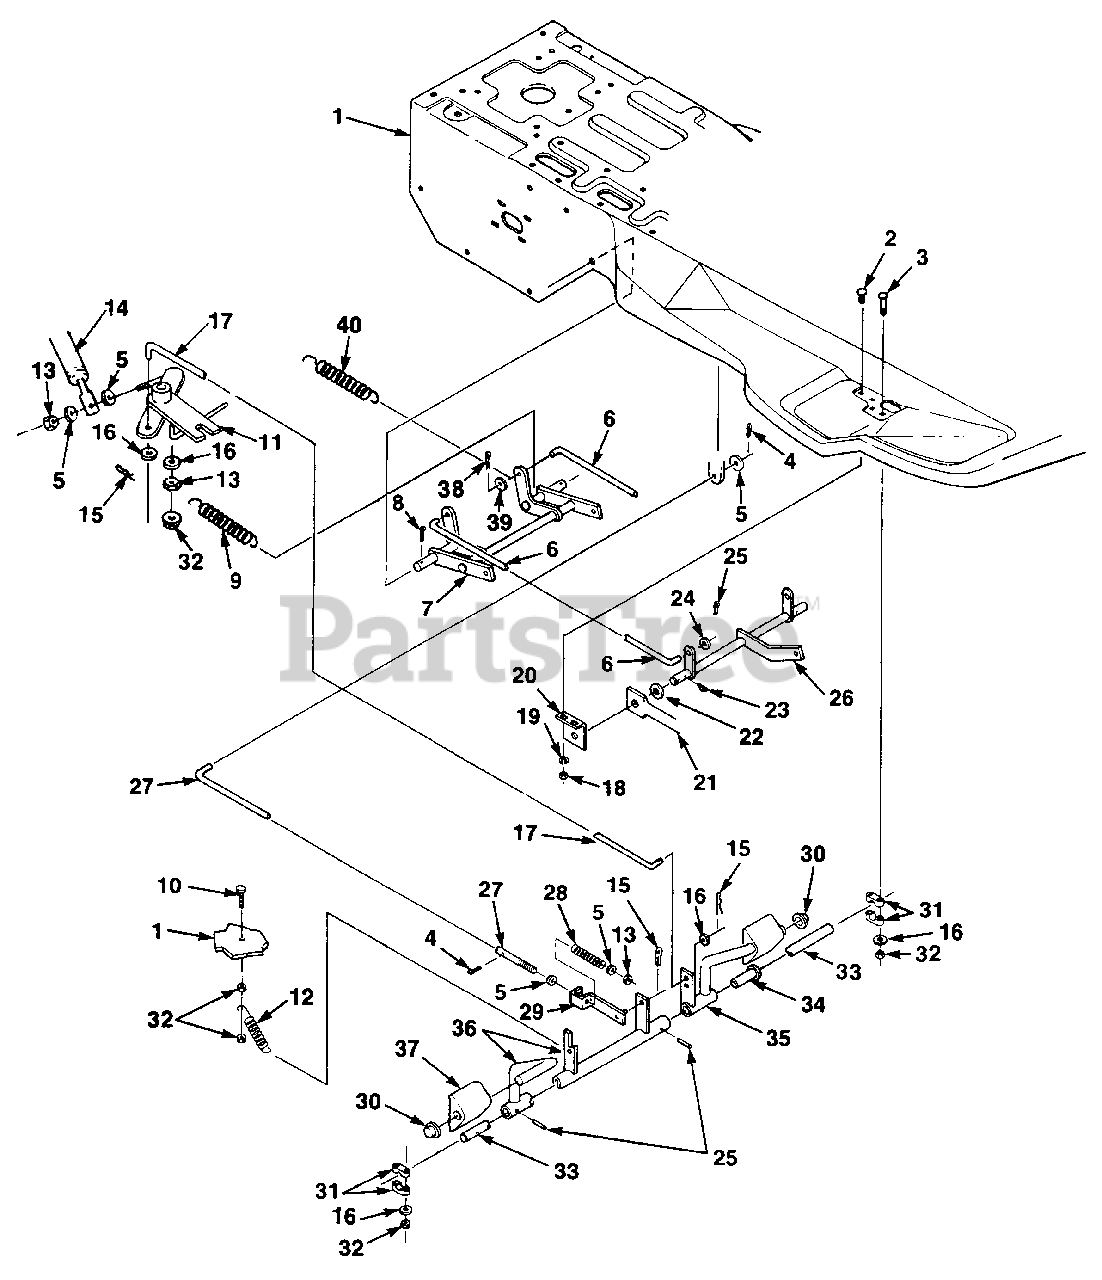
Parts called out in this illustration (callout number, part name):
2	BOLT- Carr. 1/4-20 x 5/8
3	BOLT- 1/4-20 x 1 1/2
4	PIN- Cotter
5	WASHER- 5/16 Plain
6	ROD- Deck lift
7	HANGER- Rear
8	PIN- Cotter
9	SPRING- Extension
10	SCREW- 1/4-20 x .625
11	ARM- Pivot
12	SPRING- Extension
13	NUT- Hex 5/16-18
15	PIN- Cotter
16	WASHER- 1/4"
17	ROD- Clutch
18	NUT- Hex 1/4-20
19	WASHER- Lock 1/4
21	SUPPORT- Front axle
22	WASHER- Flat 1/2
23	PIN- Cotter
24	WASHER- Flat 3/8
25	PIN- Cotter
26	HANGER- Front
27	ROD- Brake
28	SPRING- Brake
29	BRACKET- Brake spring
30	NUT- Push 5/8
32	NUT- Centerlock hex 1/4-20
33	PEDAL SHAFT
35	PEDAL- Clutch
36	PEDAL- Brake
37	PEDAL- Rubber
38	PIN- Cotter
39	WASHER- Plain
